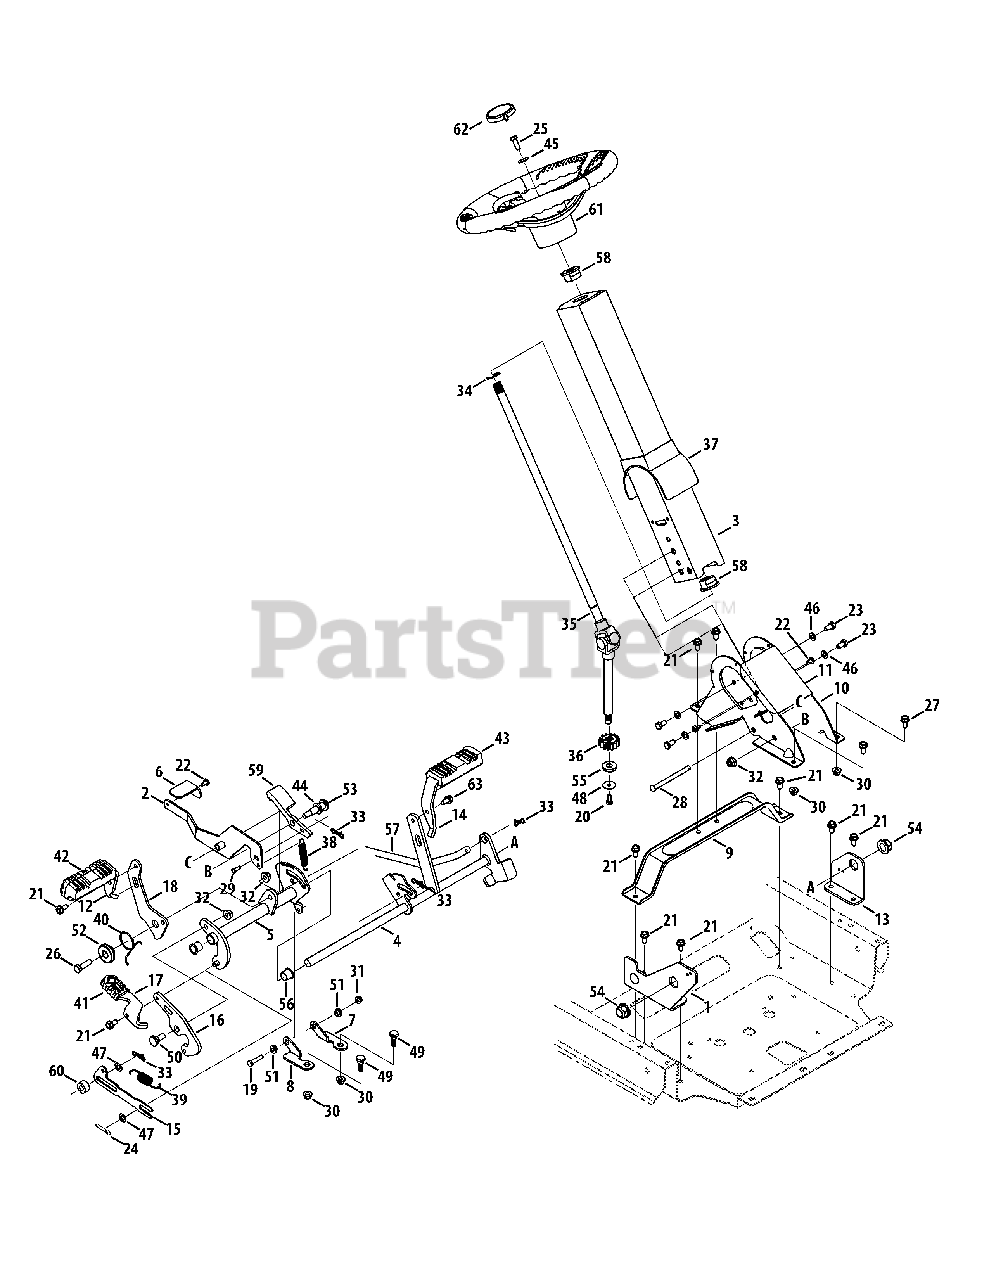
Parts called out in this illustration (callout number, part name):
1	Support Bracket Assembly RH
2	Brake Pedal Assembly
3	Steering Column Assembly
4	Brake Pedal Assembly
5	Drive Pedal Assembly
6	Tilt Steering Pedal
7	Speed Bracket LH
8	Speed Bracket RH
9	Steering Support Bracket
10	Lower Steering Wheel Column
11	Lower Column Cover
12	Drive Pedal
13	Support Bracket LH
14	Brake Pedal
15	Return to Neutral Link
16	Reverse Pedal Bracket
17	Reverse Pedal
18	Forward pedal Bracket
19	Hex Head Screw 1/4-20 x 1.25
20	Hex Head Screw 1/4-20 x .625
21	Hex Washer Screw 5/16-18 x .750
22	Screw 1/4-20 x .5
23	Hex Screw 5/16-18 x .625
24	Cotter Pin .125 x .75
25	Hex Screw 5/16-24 x.875
26	Hex Screw 3/8-16 x 1.25
27	Hex Screw 5/16-18 x .75
28	Clevis Pin 5/16 x 4.135
29	Clevis Pin .224 Dia. x .625
30	Flange Lock Nut 5/16-18
31	Flange Lock Nut 1/4-20
32	Flange Lock Nut 3/8-16
33	Bow-Tie Cotter Pin 72
34	E-Ring .750
35	Steering Shaft
36	14-Tooth Spur Gear
37	Column Cover
38	Extension Spring .500 Dia. x 2.733 Lg.
39	Extension Spring .70 OD x 3.035 Lg.
40	Torsion Spring 1.00 ID x .22
41	Reverse Pedal Pad
42	Forward Pedal Pad
43	Brake Pedal Pad
44	Flat Washer .535 x .930 x .090
45	Bell Washer .340 x .872 x .060
46	Flat Washer .330 x .630 x .064
47	Thrust Washer .375 x .700 x .030
48	Flat Washer .265 x 1.00 x .030
49	Shoulder Screw 5/16-18 x .437 x .268
50	Shoulder Bolt 3/8-16 x .500 x .270
51	Shoulder Spacer .375 x .625 x .20
52	Shoulder Spacer 1.50 x .38 x .38
53	Shoulder Screw 3/8-16 x .496 x 1.445
54	Hex Flange Bearing
55	Hex Flange Bearing 7/16
56	Flange Bearing .63 ID x .695 OD x .06
57	Front Brake Rod
58	Flange Bearing .63 ID x 1.50
59	Cruise Latch
60	Spacer .385 ID x .875 OD x .458
61	Steering Wheel Assembly
62	Steering Wheel Cover
63	Hex Cap Screw 5/16-18 x 1.0 Gr. 5
